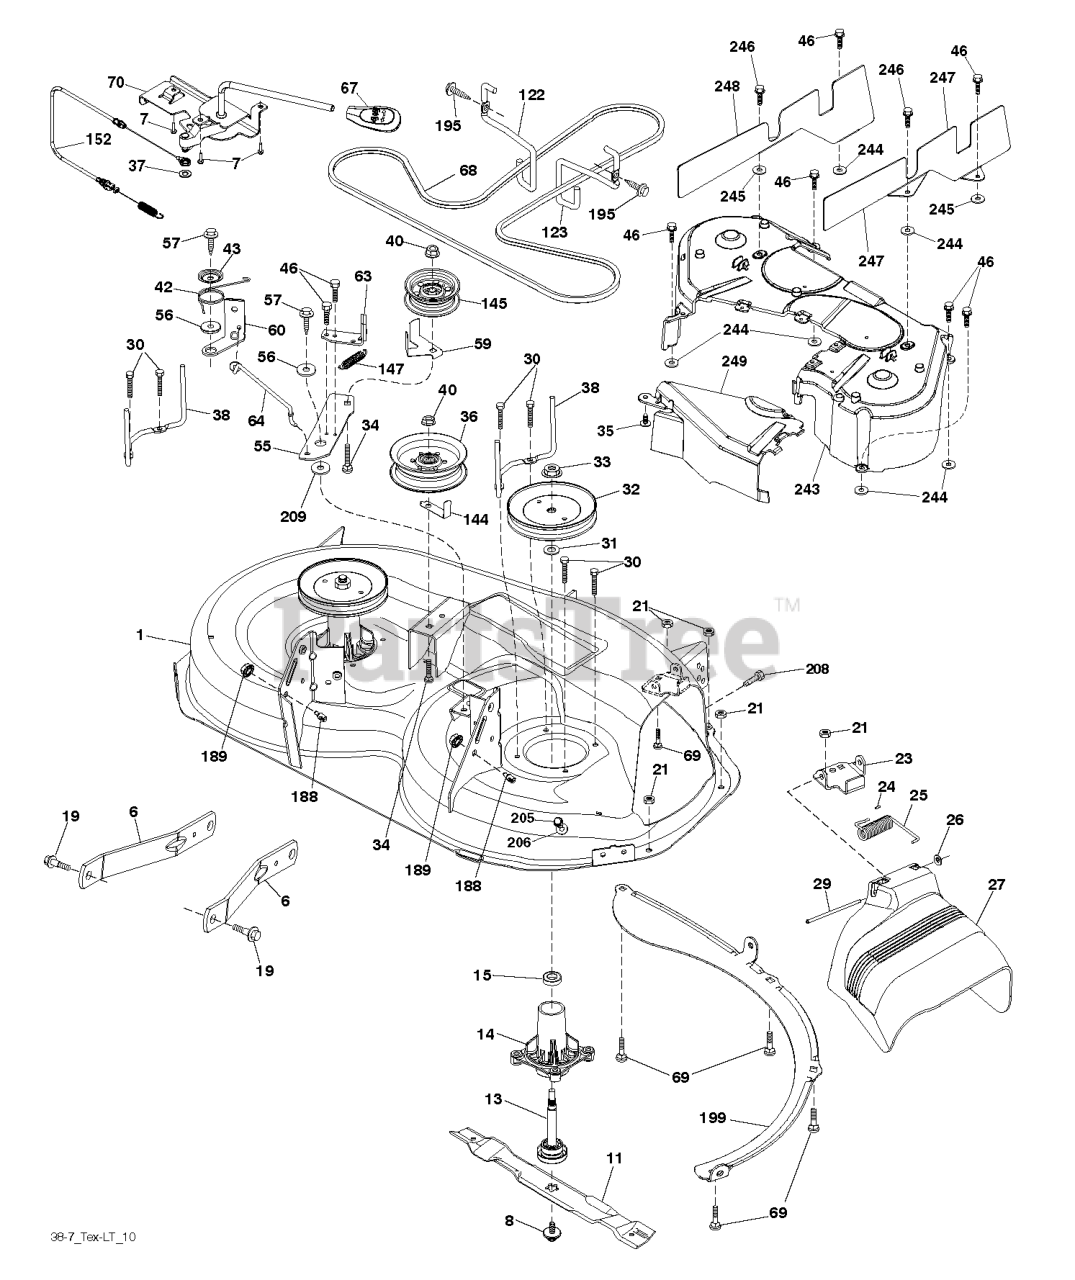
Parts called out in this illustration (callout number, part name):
1	HOUSING
6	ARM.SUSPENSION.MOWER.R
7	SCREW.#10 X 0.750.BOS
8	BOLT.WASHER.ASM.7/16-2
11	BLADE 38" PREMIUM
13	SHAFT.ASM.MDRL.N/GREASE.38
14	RP.HOUSING.MANDREL.4PT.
19	BOLT.SHOULDER
21	LOCKNUT
23	BRKT.DEFLECTOR.38"2005+
24	CAP-SLEEVE LT
25	SPRING.TORSION.DEFLECT
26	NUT PUSH M
27	SHIELD ASM.DFLCTR MWR.38-7"BLK
29	ROD.HINGE
30	SCREW, WASHER HEAD
31	WASHER.SPACER.MANDREL
32	PULLEY.MANDREL.5.0.PD.38"
33	NUT.FLANGE.LOCK.TOP
34	BOLT.3/8-16X1.50
35	FASTENER.XMAS.TREE
37	WASHER
38	KEEPER BELT LH MANDREL
40	NUT LOCK FLG 3/8-16 UNC
42	SRPING.TORSION.RETAINE
43	SPRING.TORSION.BRAKE
46	SCREW.1/4-20X5/8
56	SPACER.RETAINER
57	SCREW 3/8-16X1
59	GUARD, BELT
60	ARM BRAKE MOWER RH 38"
63	RP ARM.BRAKE.MOWER.38"LH.TEX
64	LINK BRAKE
67	HANDLE.CLUTCH.CABLE.LT
69	BOLT
70	CLUTCH.ASM.MANUAL.LT.PRED
122	KEEPER BELT ENGINE LH
123	KEEPER BELT RH
144	KEEPER BELT
145	PULLEY.IDLER.48"PRIMARY
147	SPRING RETURN
152	CLUTCH CABLE
188	STUD.FASTNER.W/ANTI-ROTATE
189	NUT LOCK HEX FLANGE 5/16-18
195	SCREW, 3/8-16X3/4
199	BAFFLE.VORTEX.FRONT.38"
205	SCREW
208	SCREW 3/8-16X1/2
209	WASHER 12/32X2X10GA
243	COVER DECK 38-7
244	PALNUT 1/4
245	WASHER 5/16"
246	SCREW, 5/16-18 X 1/2
249	COVER CABLE CLUTCH
